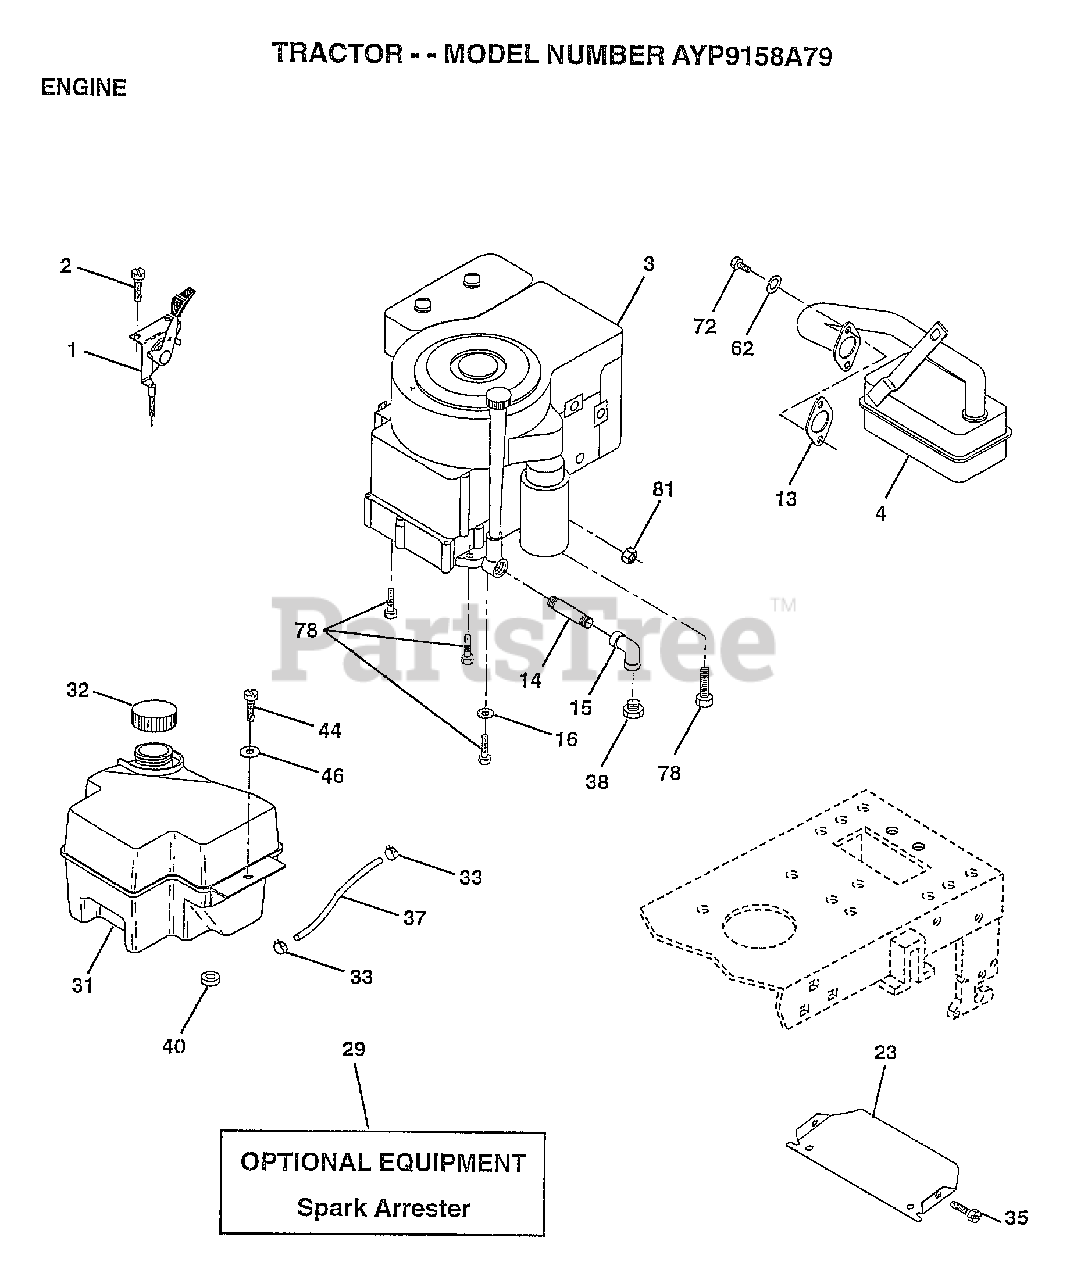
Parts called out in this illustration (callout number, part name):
1	CONTROL THROTTLE
2	SCREW LT
4	MUFFLER
13	GASKET ENG 1 313 LD TIN PLATED
14	PIPE NIPPLE
15	ELBOW
16	LOCKWASHER
23	SHIELD-HEAT
32	CAP ASM FUEL
33	HOSE CLAMP
35	SCREW
37	LINE FUEL
44	SCREW HEX CRT
46	WASHER
49	SCREW GTV
62	LOCKWASHER
72	SCREW
78	SCREW
81	NUT
